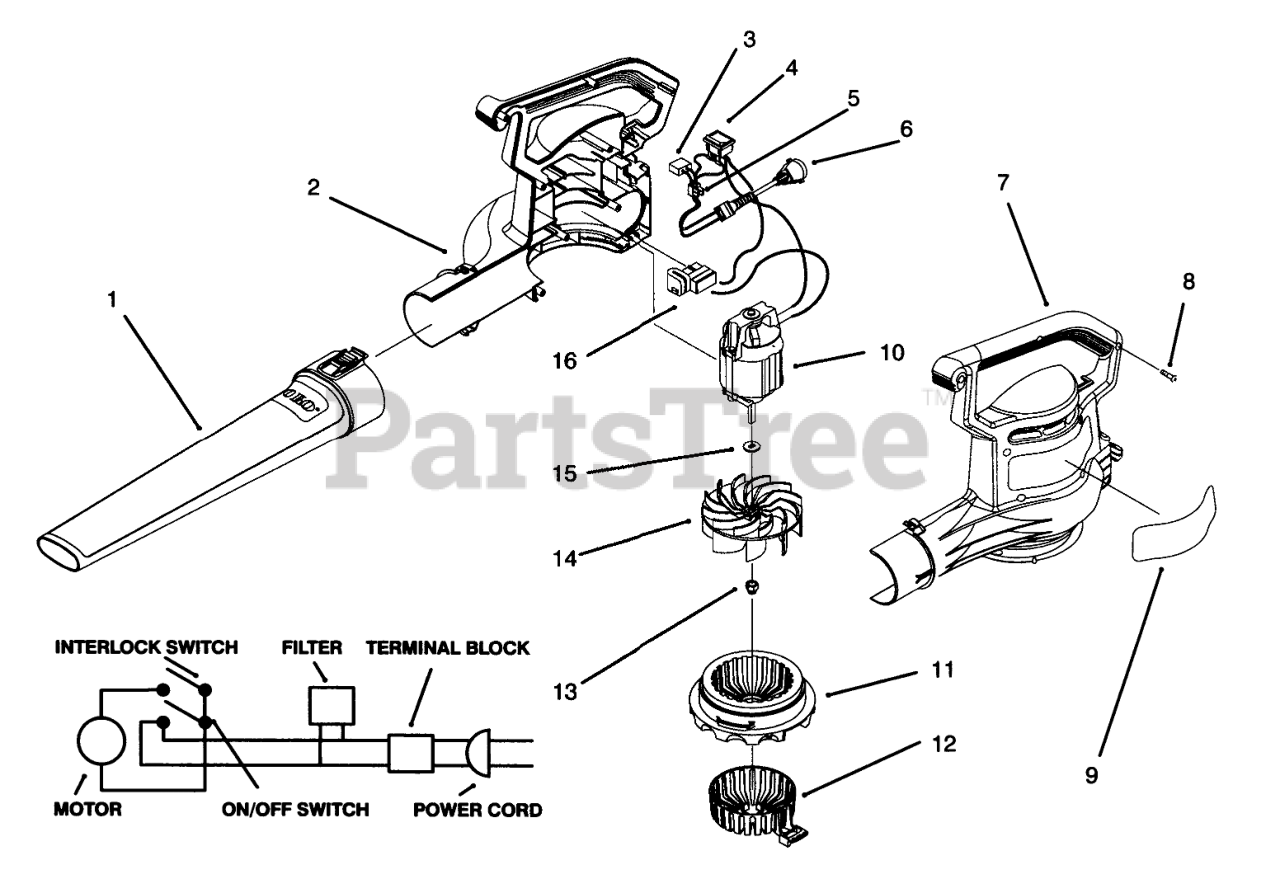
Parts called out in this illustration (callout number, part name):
1	TUBE - BLOWER SHORT
3	Block-Terminal
4	SWITCH - POWER
5	FILTER - RFI
6	CORD - POWER
7	HOUSING, LH - 230V BLOWER
8	Screw
9	DECAL, LOGO, SUPRBLWR
10	MOTOR, 230V SUPER BLOWER
11	CHOKE - AIR, RED
12	COVER - INLET, W/HOLE
13	NUT - IMPELLER
14	IMPELLER, BLOWER
15	WASHER
16	SWITCH, INTERLOCK
